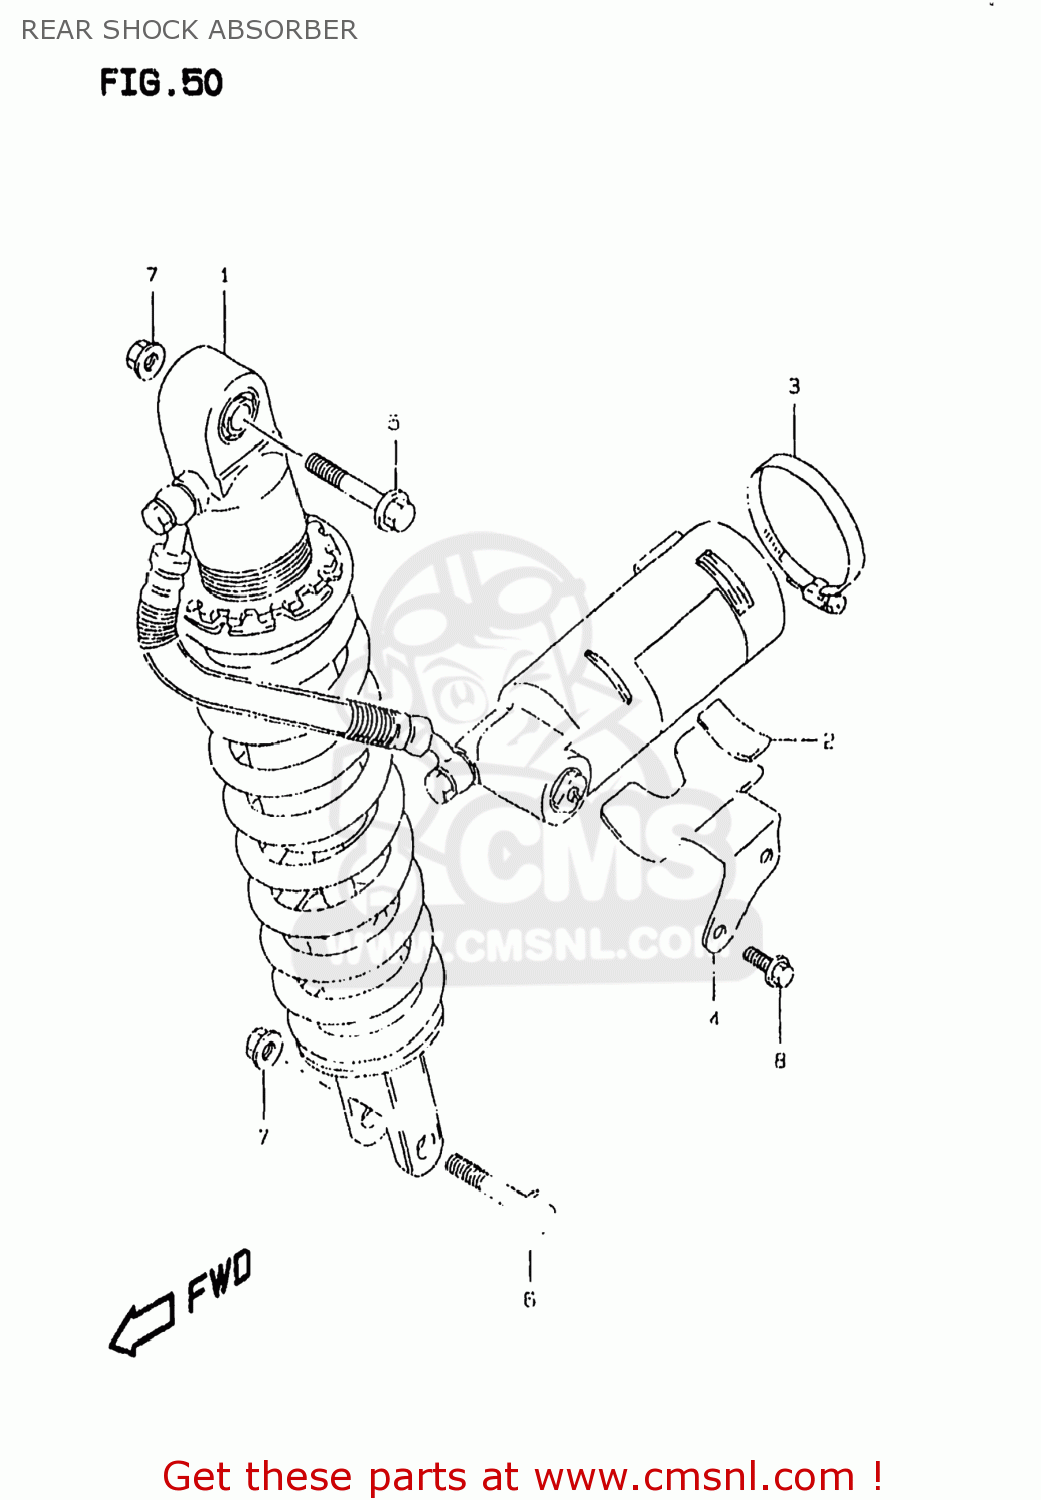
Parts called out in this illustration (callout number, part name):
1	ABSORBER ASSY,RR SHOCK
2	CUSHION
3	CLAMP
4	BRACKET,RESERVOIR TANK
5	BOLT,RR SHOCK ABSORBER
6	BOLT,RR SHOCK ABSORBER
7	NUT
8	BOLT
